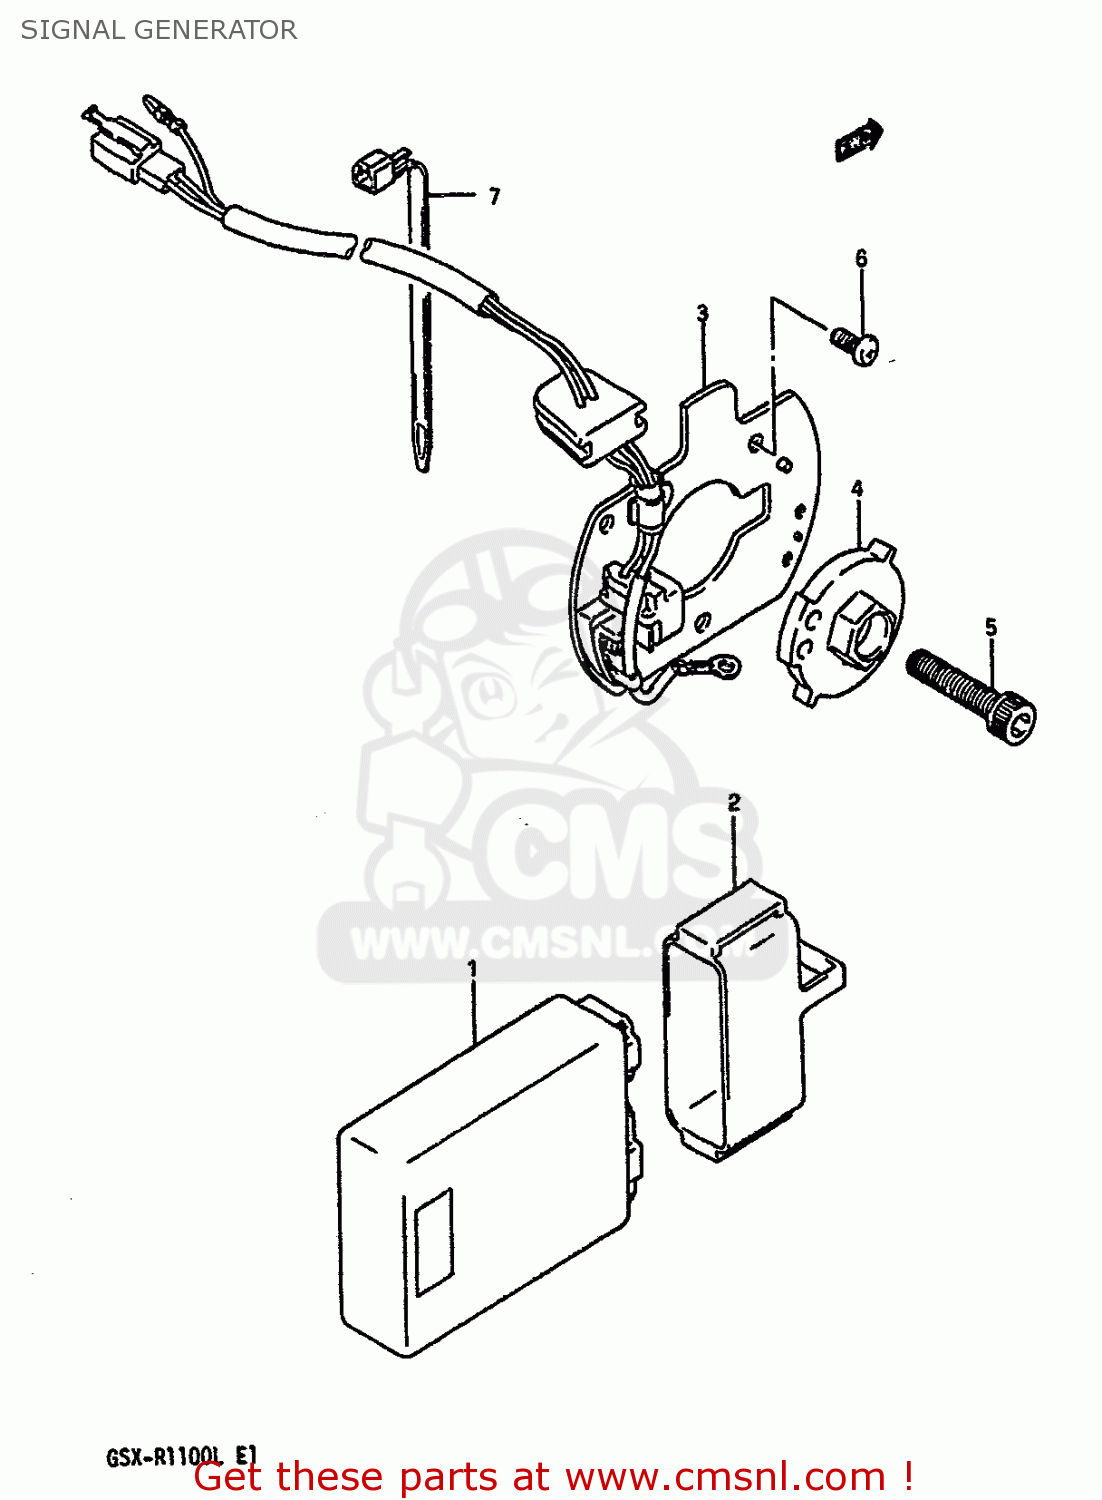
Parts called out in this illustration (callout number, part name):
1	IGNITER
2	CUSHION,IGNITER
3	GENERATOR ASSY,SIGNAL
4	ROTOR,SIGNAL
5	BOLT
6	SCREW
7	CLAMP(L:125)
